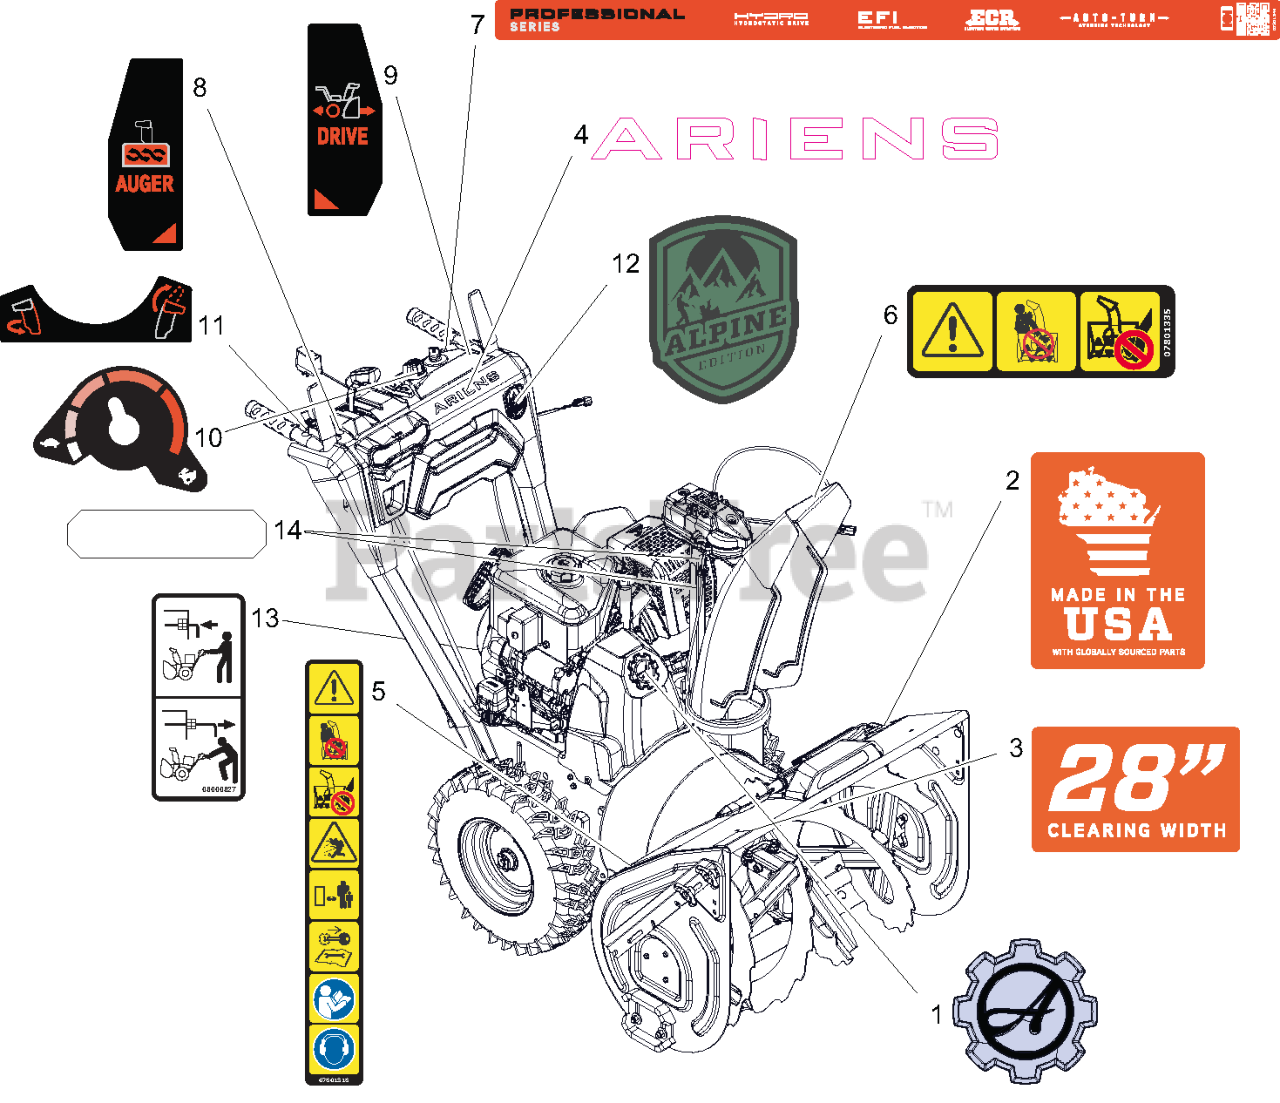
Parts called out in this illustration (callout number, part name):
1	DECAL, ARIENS - GEAR BADGE
2	DECAL- MADE IN USA
3	DECAL- CLEARING - 28
4	DECAL- ARIENS - 7.46"
5	DECAL- SAFETY - DANGER
6	DECAL- DANGER
7	DECAL- DASH - PRO EFI ECR
8	DECAL- CONTROL - AUGER
9	DECAL- CONTROL - DRIVE WHEEL
10	DECAL- CONTROL - EFI SPEED
11	DECAL- CONTORL - ECR
12	DECAL- BADGE - ALPINE
13	DECAL, BYPASS
14	DECAL,REFLECTIVE,GEAR COVER
